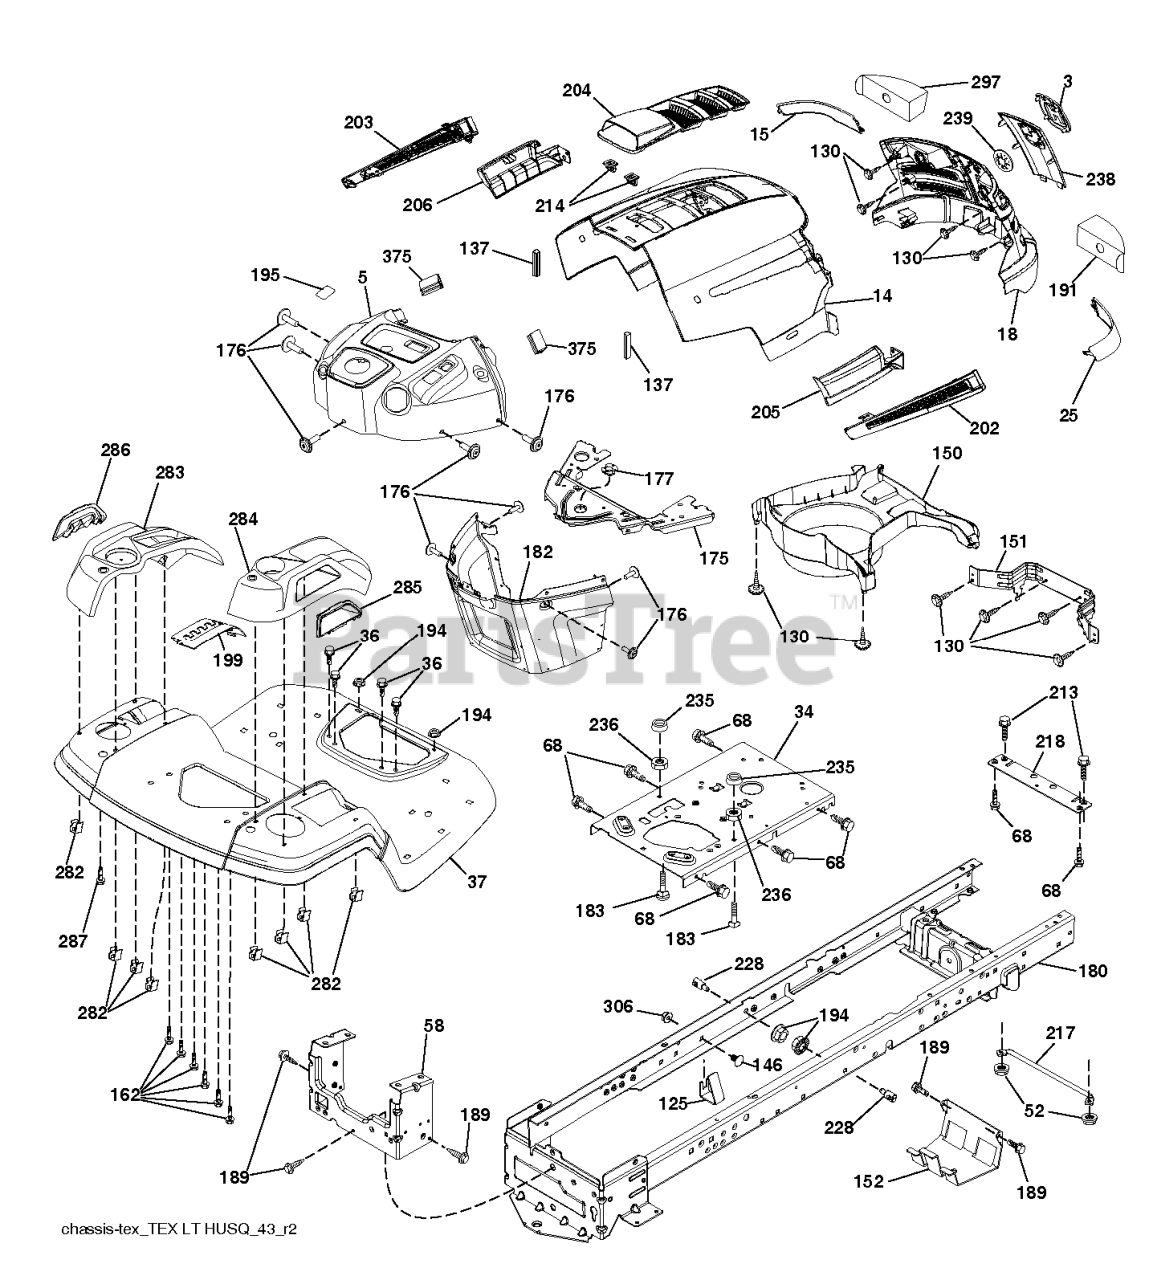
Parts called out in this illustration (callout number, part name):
2	VALVE STEM LT
3	RIM.ASM.8X5.FRONT.SILVER
4	TUBE.16X6.5/7.5-8
5	TIRE.FRONT.K505.16X6.5-8.SVC
6	FITTING LT.
7	BEARING.FLANGE
8	CAP, AXLE BLK
9	TIRE.REAR.K505.23X10.5-12.SVC
10	TUBE.23X9.5-12
11	RIM ASM.12"REAR.SILVER.SERVICE
12	CAP.HUB.GT.PM.BLACK
